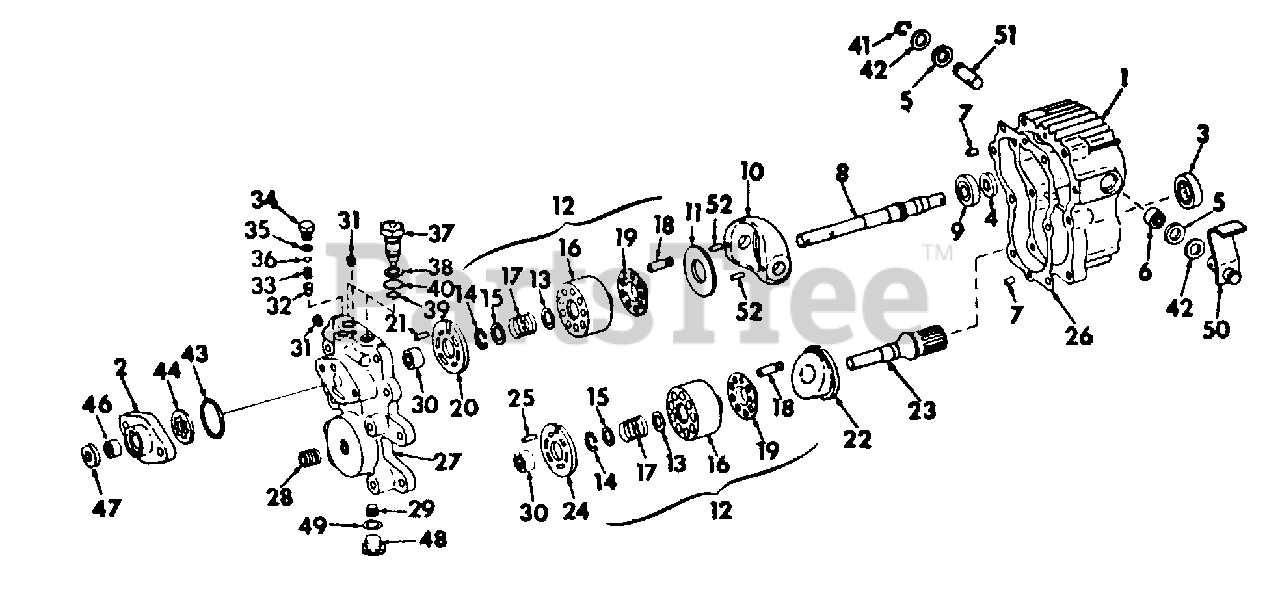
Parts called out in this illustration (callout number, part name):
1	Housing Assy
2	Housing, Charge Pump
3	Bearing, Hyd Pump Shaft Roller
5	Seal, Lip
6	Bearing, Needle
7	Pin, Transmission Housing
8	Shaft, Transmission Hyd Pump
9	Bearing, Ball
10	Swashplate, Hyd Pump
11	Plate, Hyd Pump Swashplate Thrust
12	Kit, Cylinder Block Motor and Pump
13	Washer, Spring Front
14	Ring, Hyd Cyl Block Spring Rear Washer Snap
15	Washer, Hyd Cyl Block Spring Rear
16	Block, Cylinder
17	Spring, Hyd Cylinder Block
18	Piston Assy, Hyd Pump and Motor
19	Retainer, Hyd Piston Slipper
20	Plate, Hyd Cyl Block Valve
21	Pin, Hyd Pump Cyl Block
22	Swashplate, Hyd Motor
23	Shaft, Transmission Hyd Motor
24	Plate, Hyd Motor Cyl Block Valve
25	Pin, Hyd Motor Cyl Block
26	Gasket, Transmission Housing
27	Housing, Transmission Center
28	Fitting, Center Housing
29	Plug, 1/4-18 Automotive, Hex Soc Hd Pipe
30	Bearing, Center Housing Needle
31	Plug, 1/8-27 Automotive, Hex Soc Hd Pipe
32	Cone, Relief Valve
33	Spring, Charge Relief Valve
34	Plug, Relief Valve
35	O-Ring, 13/32 X 9/16 X 5/64 Relief Valve Plug
37	Valve Assy, Center Housing Check
38	Washer, Check Valve Housing
39	O-Ring, 5/8 X 3/4 X 1/16
40	O-Ring, 3/4 X 15/16 X 3/32 Check Vlve Housing, Large
41	Ring, Trunnion Shaft Snap
42	Washer, Trunnion Shaft Seal Retaining
43	O-Ring, 2-3/8 X 2-1/2 X 1/16 Calss 5
44	Rotor Assy, Charge Pump
46	Rearing, Charge Pump Housing Needle
47	Seal, Lip
48	Plug, 3/4-16 C-Z Str Thd
49	O-Ring, 41-64 X 13/16 X 3/32
50	Shaft Assy, Trunnion
51	Shaft, Trunnion
52	Pin, 3/16 X 5/8 Coiled Spring
